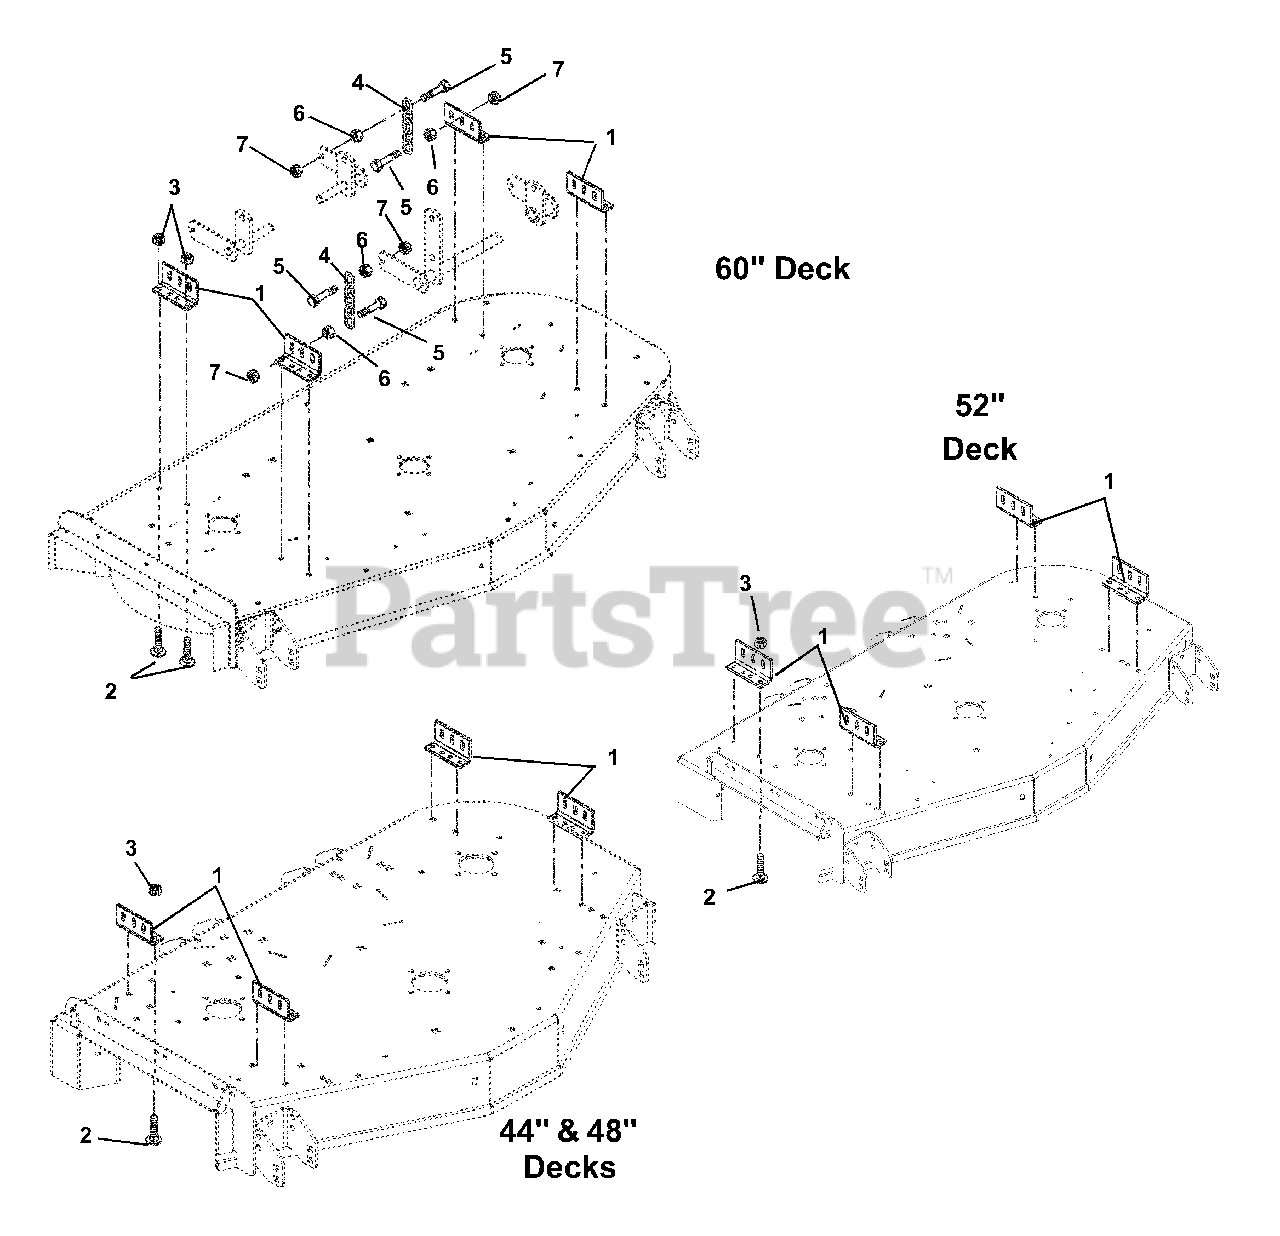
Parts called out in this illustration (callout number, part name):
1	Bracket, Mower Mounting
2	Bolt, Round Head Square Neck .38-16 x 1.00 Grade 2
3	Nut, Locking Top Flange .38-16
4	Chain, Link
5	Bolt, Hex M12-1.75 x 55 Grade 5
6	Nut, Spin Lock Flange M12-1.75
7	Nut, Locking Top Flange M12-1.75
